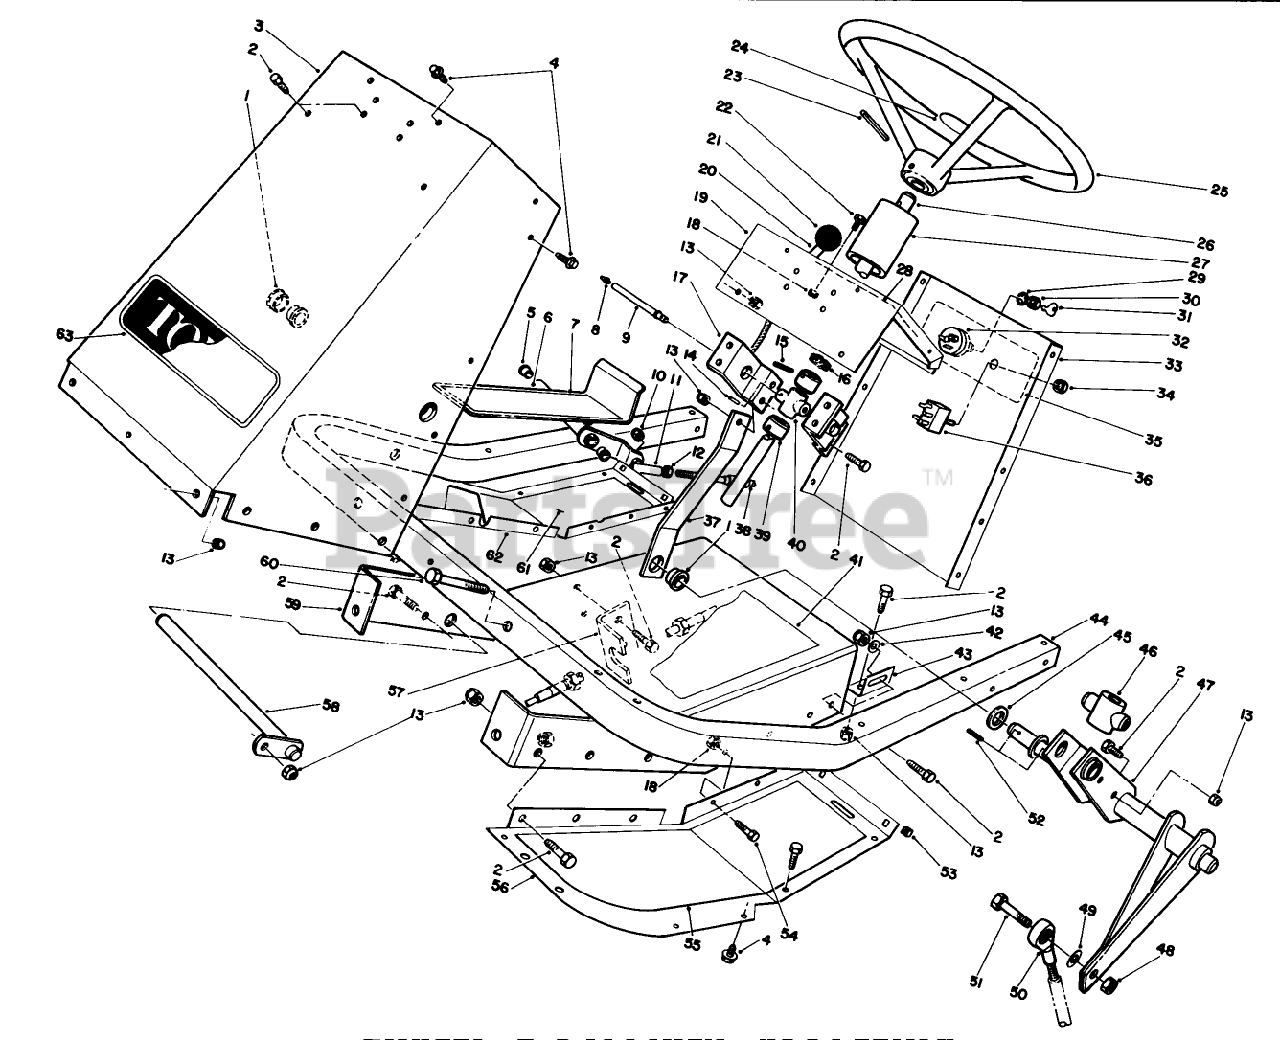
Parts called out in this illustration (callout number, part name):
1	BEARING-FLANGE
2	SCREW-HH
4	SCREW-HHFTF
5	BUSHING-FLANGE
8	FITTING-GREASE
9	TUBE ZERK
10	NUT-LOCK
11	JOINT-BALL
12	NUT-JAM
13	NUT-LOCK, NI
14	3/32 X 9/16 ROLL PIN
15	PIN-SPRING
16	COVER-DUST
17	BRG SUPT BRKT
18	NUT-LOCK, NI
20	CONTROL-CHOKE,THROTTLE
22	SCREW-HH
23	PIN-ROLL
24	STEERING WHEEL CAP
27	STRG. SHAFT COVER
28	THROTTLE DECAL
29	WASHER-LOCK
30	NUT-HEX
32	SWITCH
39	STRG SHAFT COLLAR
40	BRG STEERING SHAFT
42	WASHER-PLAIN
43	TUNNEL BRKT
45	WASHER-THRUST
46	STEER.SHAFT FOLLOWER
48	NUT-HEX
49	WASHER-FLAT
50	BALL JOINT LH
51	SCREW-HH
52	PIN-ROLL
53	NUT-RETAINED
54	SCREW-HH
58	PEDAL.SHAFT WA
60	SCREW-HH
61	FOOT REST PAD RH
